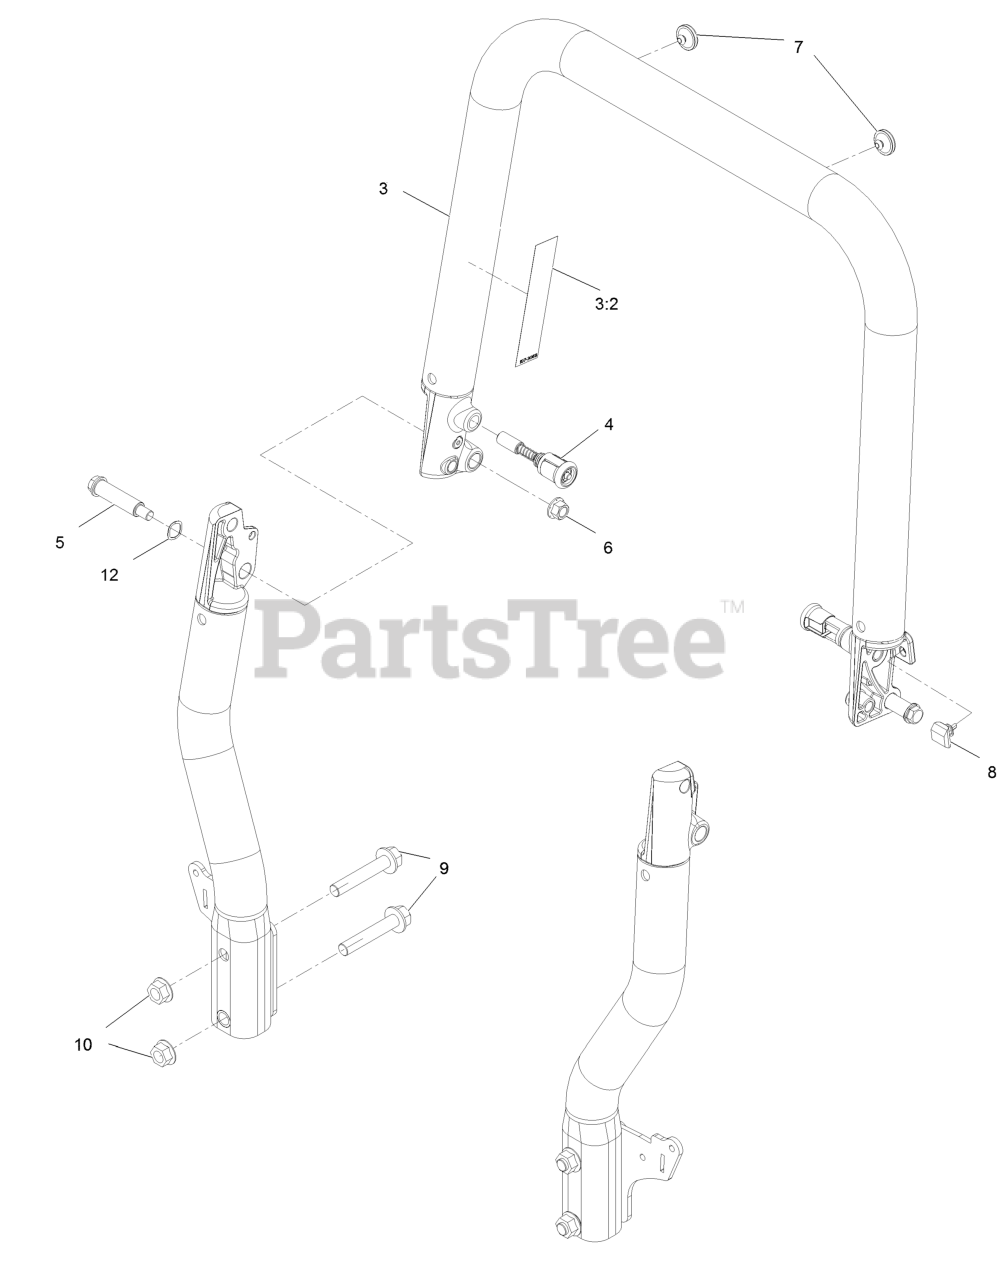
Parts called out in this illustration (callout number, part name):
3	Top Tube ASM
3:2	Decal-Warning
4	Pin-Spring
5	Bolt-Shoulder
6	Nut-Lock
7	Bumper, ROPS
8	Bumper-ROPS
9	Screw-HHF
10	Nut-Flange
12	Washer-Wave
